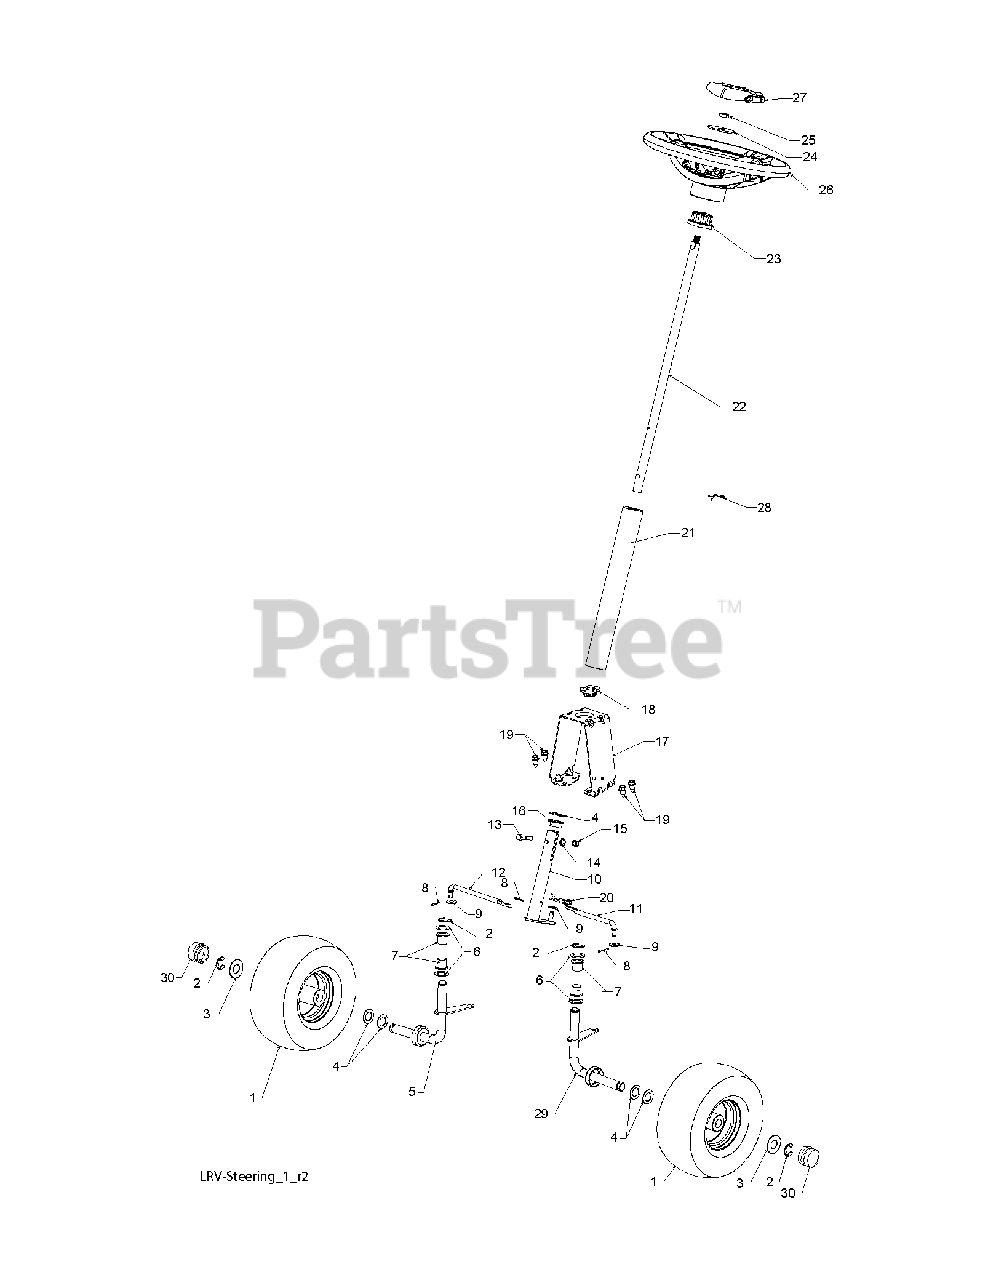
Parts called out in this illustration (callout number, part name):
1	WHEEL.ASM.FRONT.LRV.10" GRAY
2	E-RING LT
3	WASHER.HARDENED
5	SPINDLE.STEERING.RH.LRVA
7	Steering Column Bearing
8	PIN.COTTER.5/64X3/4
10	WELDMENT, LWR STRG SHAFT
11	LINK, STRNG LH LRV
12	LINK.STEERING.RH.LRV
13	HEX BOLT
15	NUT.71038.31-18.HEX.NYLOCK
16	BUSHING, STEERING SNAP
17	SUPPORT, UPPER STEERING
18	BUSHING,STEERING
19	SCREW
20	CLIP.SPRING.STEERINGG
21	FOAM.SHAFT.STEERING
23	STEERING.WHEEL.ADAPTER
24	WASHER 9/16"ID, 2 3/8""OD
25	NUT.HEX.1/2-20
26	WHEEL.STEER.STDR.498.OVRM.GRAY
27	CAP.WHL.STRNG.STDSRRD.SRS.GREY
28	RETAINER.CLIP.SPRING.S
29	WELDMENT.SPINDLE.LH.LR
30	CAP.HUB.AXLE.LRVA/B
